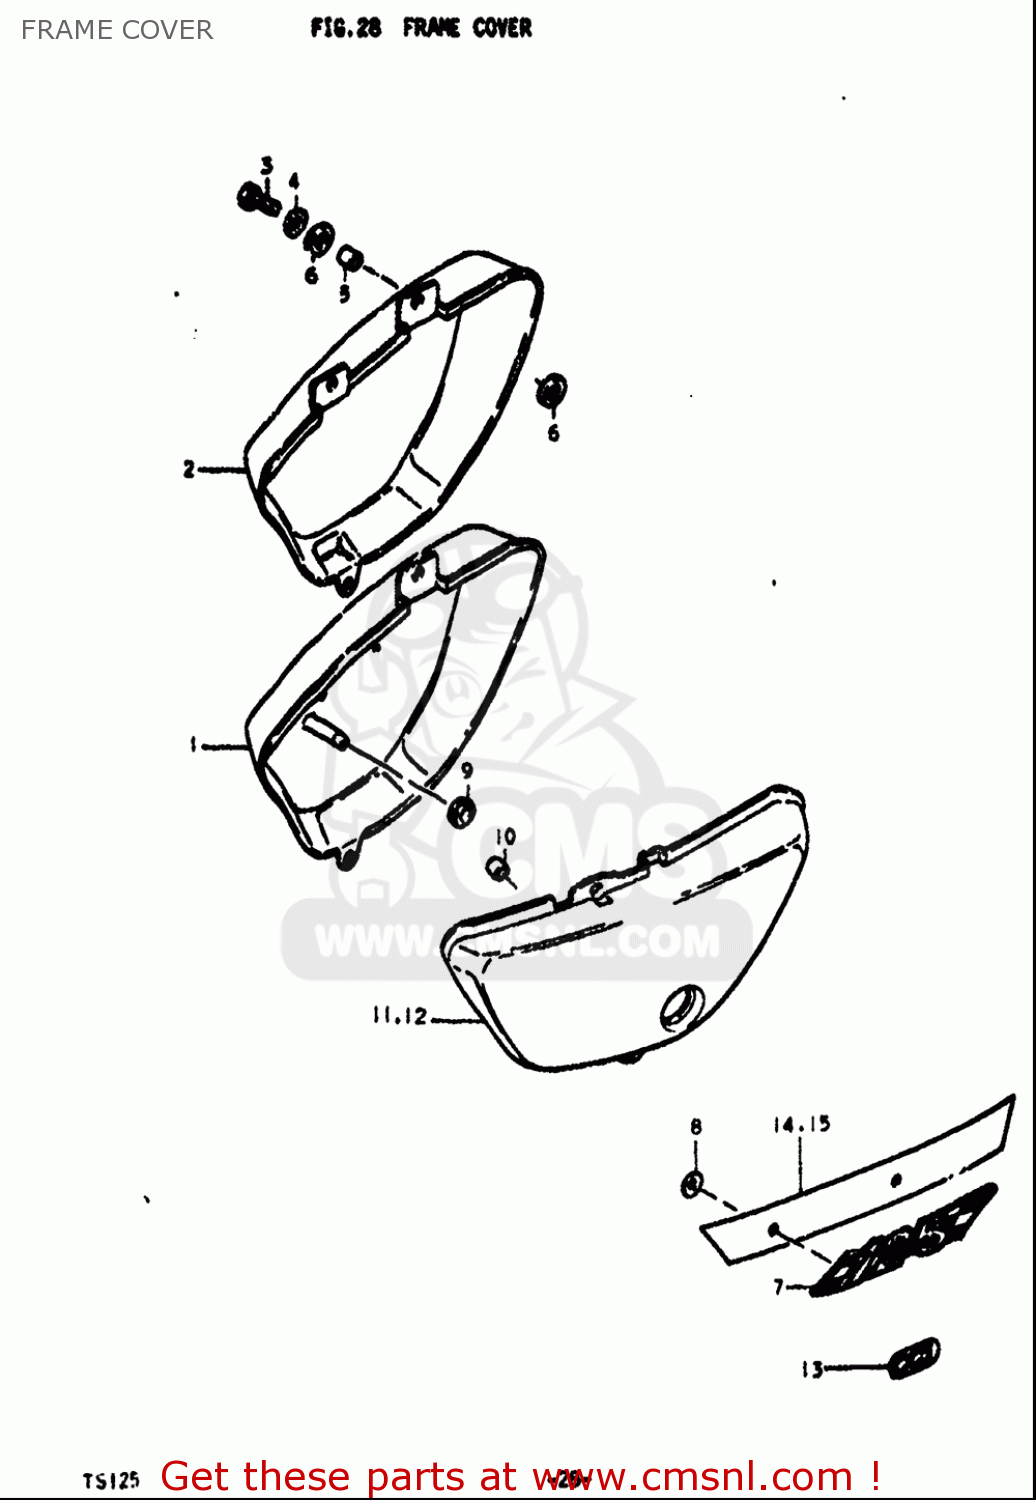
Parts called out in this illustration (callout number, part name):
3	SCREW
4	WASHER
5	SPACER(6.1X8X9.5)
6	CUSHION
8	NUT
10	CUSHION
13	EMBLEM,CCIS
